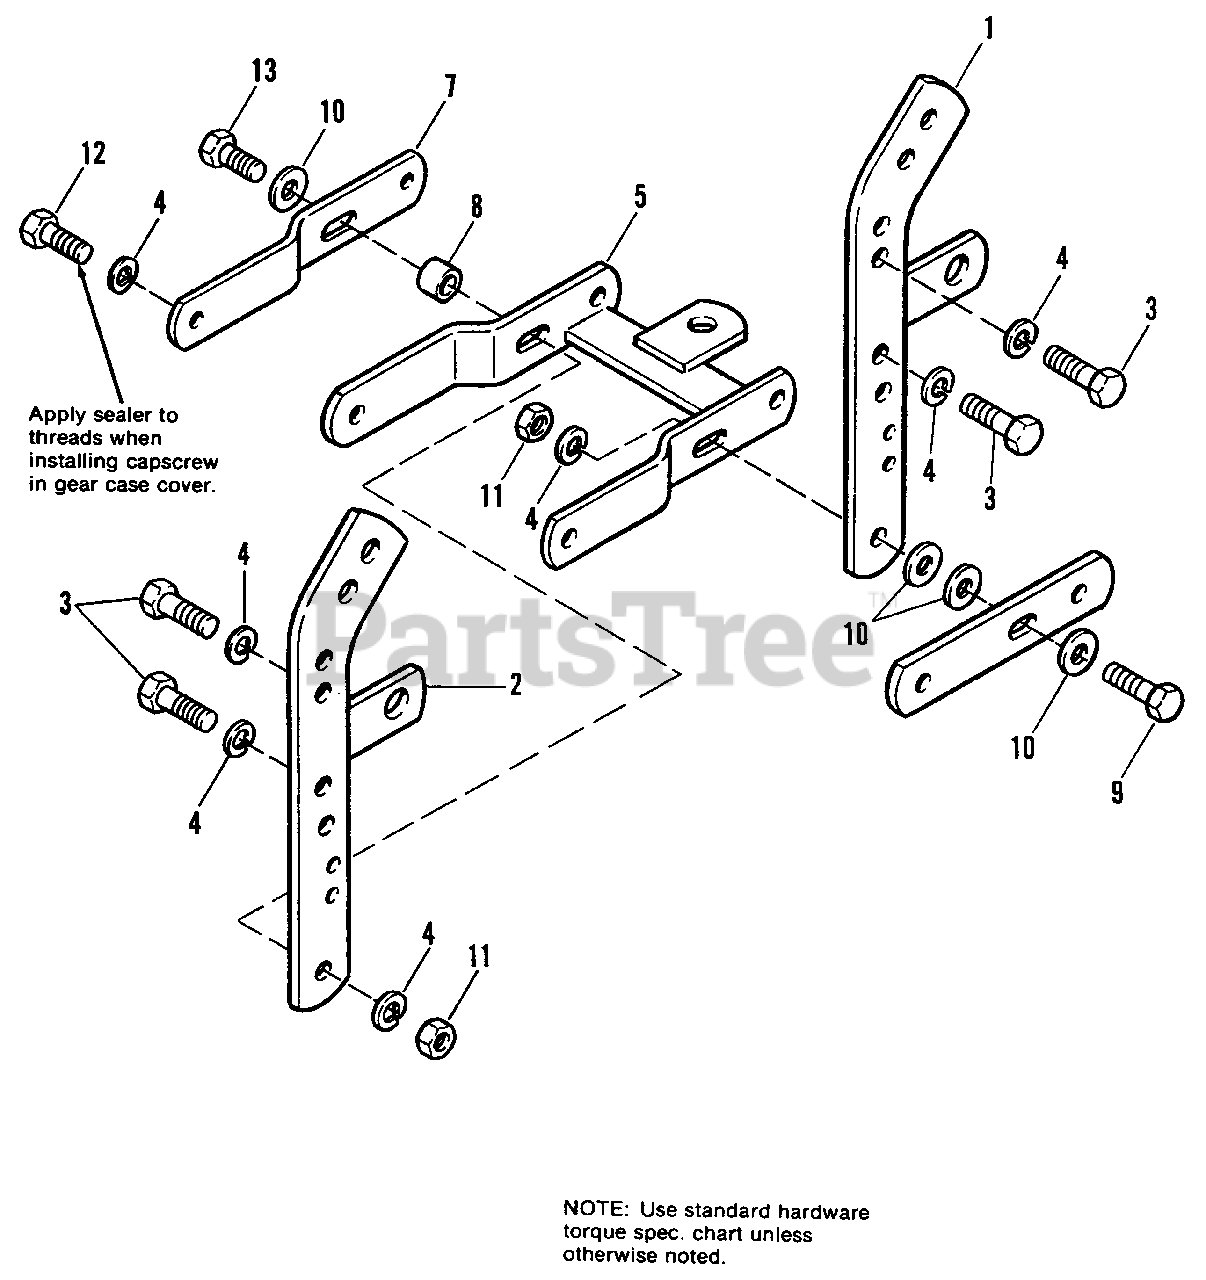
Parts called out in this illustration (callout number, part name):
1	ARM ASSY., L.H.
2	ARM ASSY., R.H.
3	CAPSCREW, Hex Hd., 7/16-14 x 1
4	LOCKWASHER, 7/16
5	DRAW BAR ASSY.
6	BAR, Pull, L.H.
7	BAR, Draw, R.H.
9	CAPSCREW, Hex Hd., 7/16-14 x 1-1/4
10	WASHER, 7/16
11	NUT, Hex, 7/16-14
12	CAPSCREW, Hex Hd., 7/16-14 x 1-3/4
13	CAPSCREW, Hex Hd., 7/16-14 x 2-1/4
